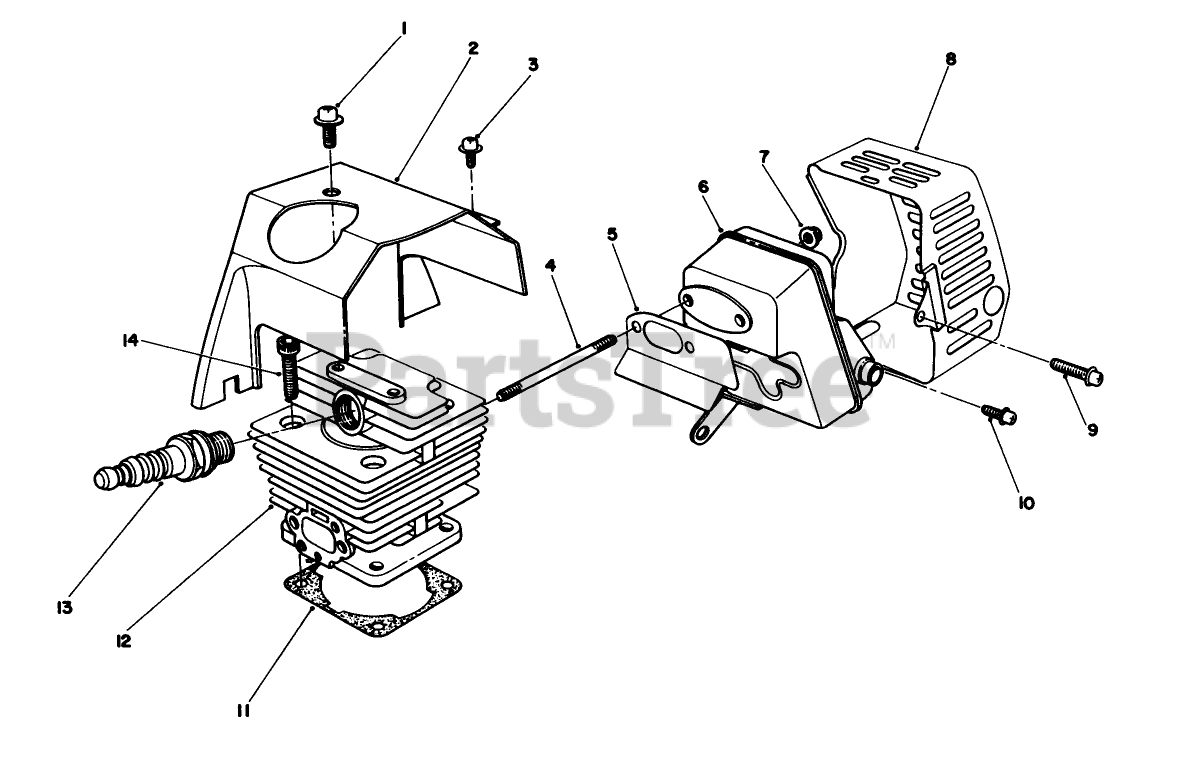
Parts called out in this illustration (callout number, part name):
6	MUFFLER
10	SCREW & WASHER
12	CYLINDER
